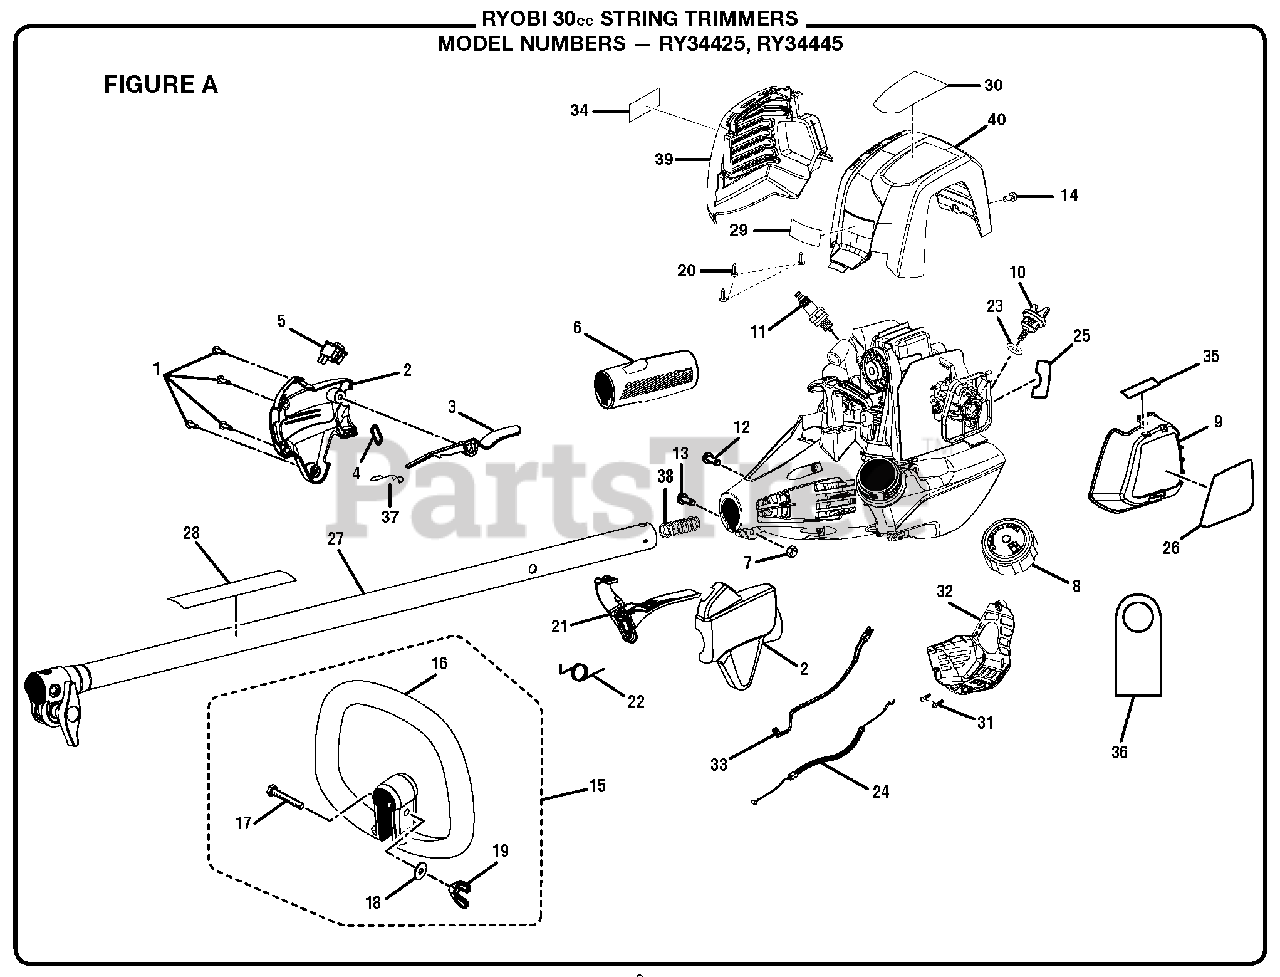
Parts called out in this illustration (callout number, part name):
1	Screw (M4 x 20 mm)
2	Control Handle Assembly
3	Trigger Lock
4	Strap Hanger
5	Switch (Momentary Contact)
6	Rear Handle
7	Hex Nut (M6.3 x 1)
8	Fuel Cap Assembly
9	Air Filter Cover
10	Oil Cap/Dipstick (Incl. Key No. 23)
11	Spark Plug (Champion RY4C)
12	Screw (#8-16 x 5/16 in.)
13	Bolt (M6 x 1 x 20 mm)
14	Screw (M5 x 11 mm)
15	Front Handle Assembly (Incl. Key No. 16-19)
16	Front Handle
17	Bolt (1/4-20 x 40 mm)
18	Washer (1/4 in.)
19	Wing Nut (1/4-20)
20	Screw (M4 x 12 mm)
21	Throttle Trigger
22	Throttle Trigger Spring
24	Throttle Cable
25	Hot Surface Label
26	Starting Label
27	Upper Boom Assembly (Incl. Key No. 28)
28	Warning Label
29	Logo Label
30	C430 Label (RY34425)
31	Screw (#6-19 x 1/2 in.)
32	CE Cover (Bottom Cover)
33	Lead Assembly (Inc. Key No. 5)
34	Combustion Warning Label
35	Choke Label
36	Oil Hang Tag
38	Compression Spring
39	Muffler Housing
40	Top Cover
